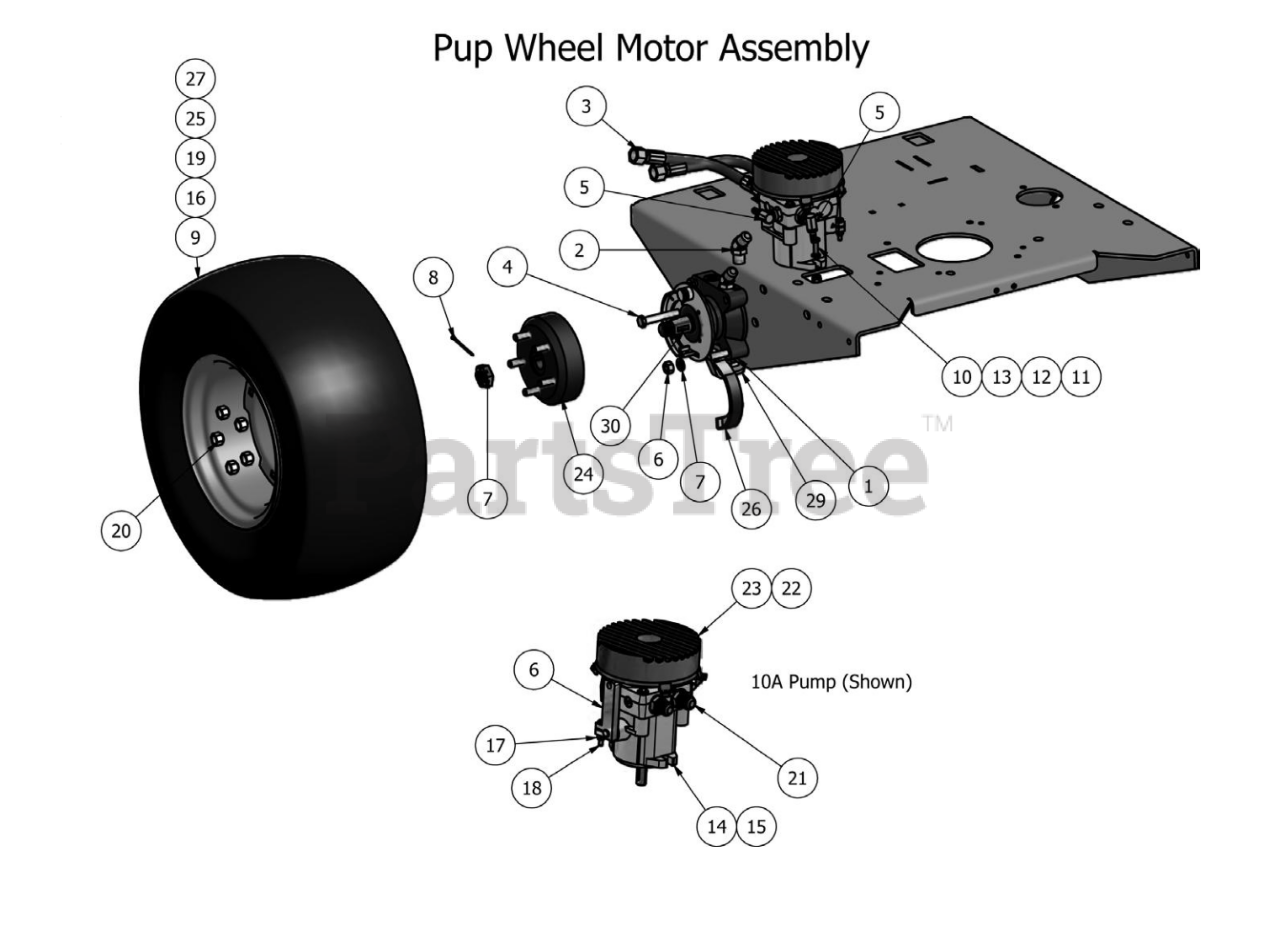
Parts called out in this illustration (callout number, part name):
1	Brake & Wheel Motor (Right)
1A	Brake & Wheel Motor (Left)
2	Hydraulic Fitting (Wheel Motor)
3	Hydraulic Hose
4	1/2" x 3" Hex Bolt
5	3/8" x 9/16" Male Fitting
6	Pup Pump Arm
7	Castle Nut
8	1/8" x 2 1/4" Cotter Pin
9	12" Rim -60"&72" Cut
10	3/8" x 1 1/2" Hex Bolt
11	3/8" Hex Nut
12	3/8" Lock Washer
13	3/8" Flat Washer
14	Hydraulic Pump (10A) Left 3KCC
15	Hydraulic Pump (10A) Right 3HCC
16	24 x 12-12 Tire 60"& 72" Cut
17	1/4" Nylock Nut
18	1/4" x 1 1/2" Bolt Straight Thread
19	24" Tire and Wheel Assembly
21	Hydraulic Fitting
22	Hydraulic Fan
24	Brake Drum
25	23 x 10.50-12 Tire & Wheel
26	Brake Shoes
27	12" Rim 48"& 52" Cut
28	23 x 10.50-12 Tire
29	Brake Lever (wheel motor) Left (Shown)
29A	Brake Lever (wheel motor) Right
30	Woodruff Key
